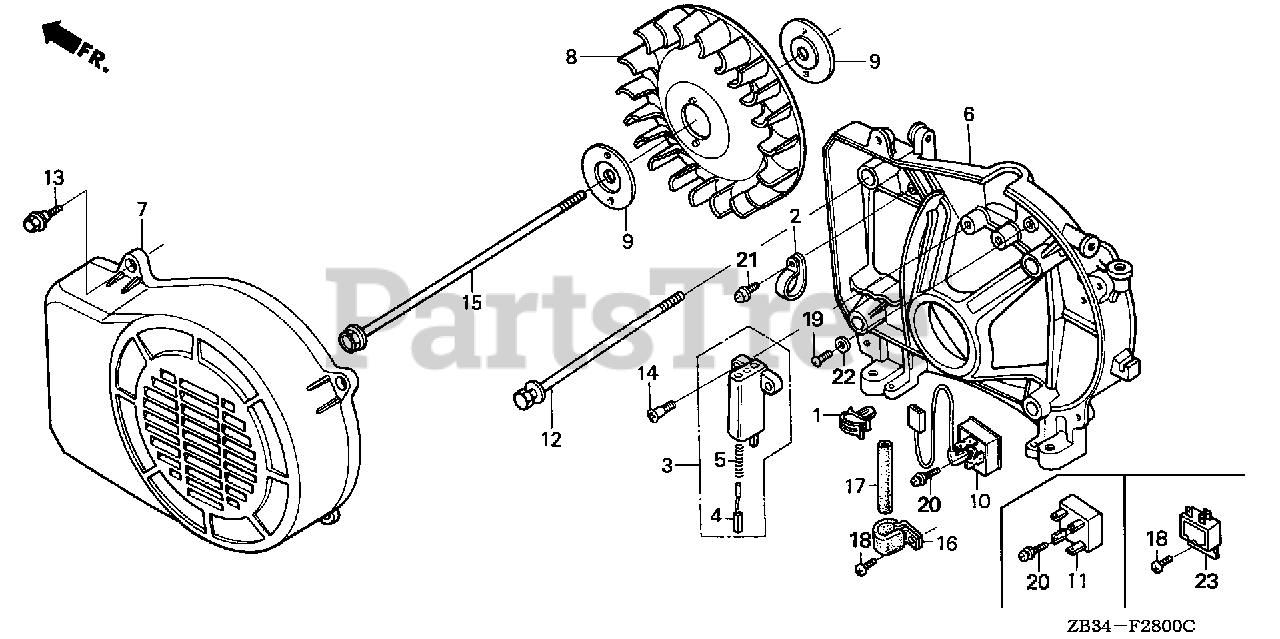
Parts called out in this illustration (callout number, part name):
1	CLAMP, D.C. CABLE
2	CLAMP C, CABLE
3	HOLDER ASSY., BRUSH
5	SPRING, BRUSH
6	HOUSING, RR.
7	COVER, GENERATOR END
8	FAN, COOLING
9	PLATE, FAN
10	DIODE, D.C. (NOT AVAILABLE)
12	BOLT, FLANGE (6X122)
13	BOLT, GENERATOR END COVER
14	BOLT, STATOR COVER SETTING
15	BOLT, FLANGE (8X160)
16	CLIP, WIRE
17	TUBE, CORD
18	SCREW, PAN (5X8)
19	SCREW, PAN (5X12)
20	SCREW-WASHER (4X18)
21	SCREW-WASHER (5X12)
22	WASHER, SPRING (5MM)
23	DIODE, D.C.
